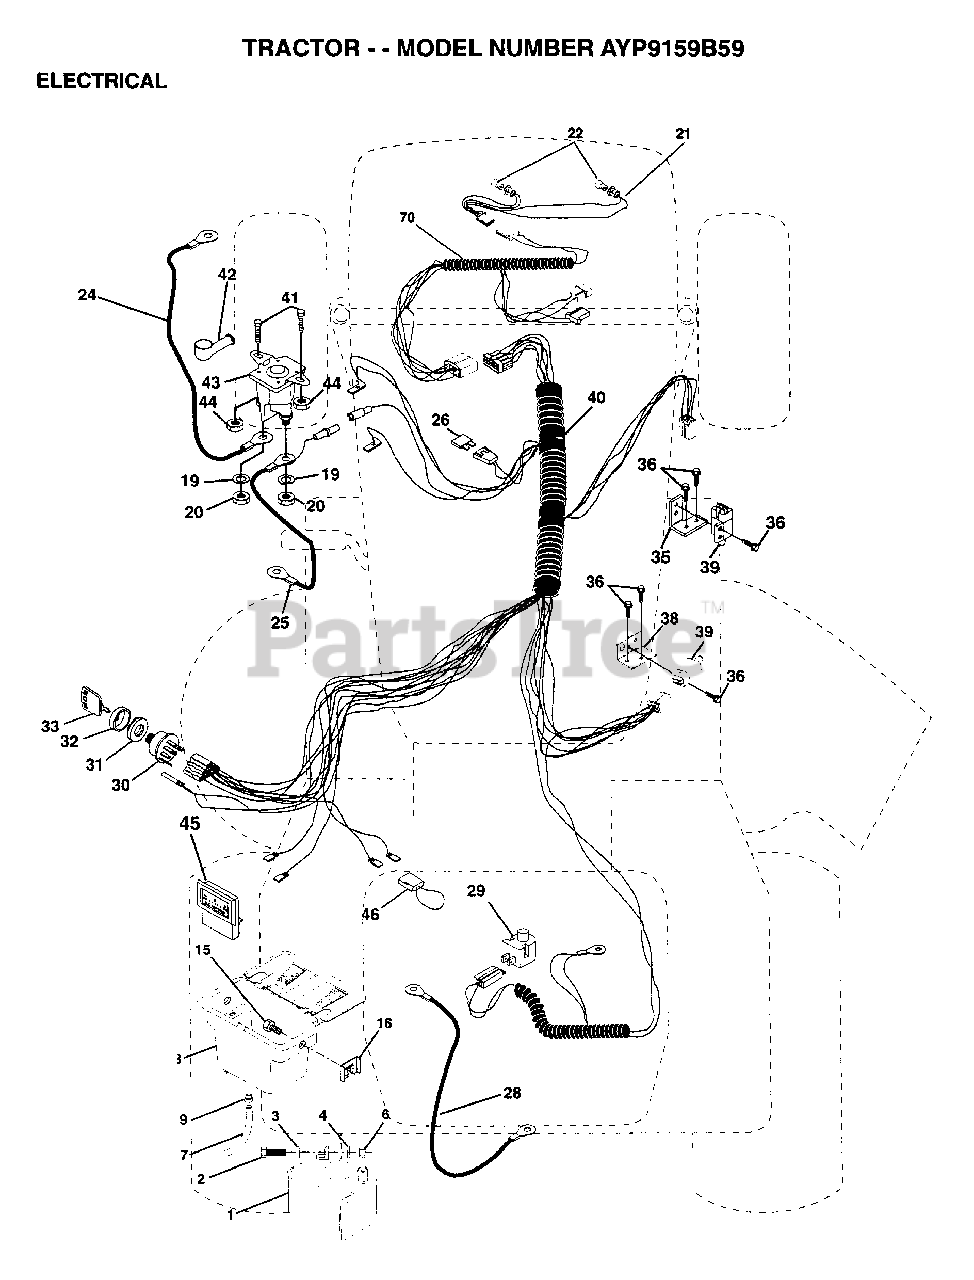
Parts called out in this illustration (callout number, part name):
2	BOLT LT
3	WASHER
4	LOCKWASHER
7	TUBE T
9	HOSE CLAMP T
15	SCREW.CAP.HEX.NYL
16	NUT.CLIP.FASTNER
20	NUT
21	"HARNESS,LIGHT SOC"
22	HEADLAMP BULB
24	"CABLE T, BATTERY"
25	CABLE.BTRY.6GA.RD
26	FUSE HYT
28	CABLE T
29	SWITCH SEAT
30	SWITCH IGN 4POS
31	NUT IGNITION
32	COVER KEY SWITCH
33	KEY
35	BRACKET LT
36	SCREW
38	BRACKET SWITCH IN
39	SWITCH INTERLOCKT
41	BOLT.HX.1/4-20
44	NUT
46	PROTECTION LOOP
70	HARNESS ENGINE
